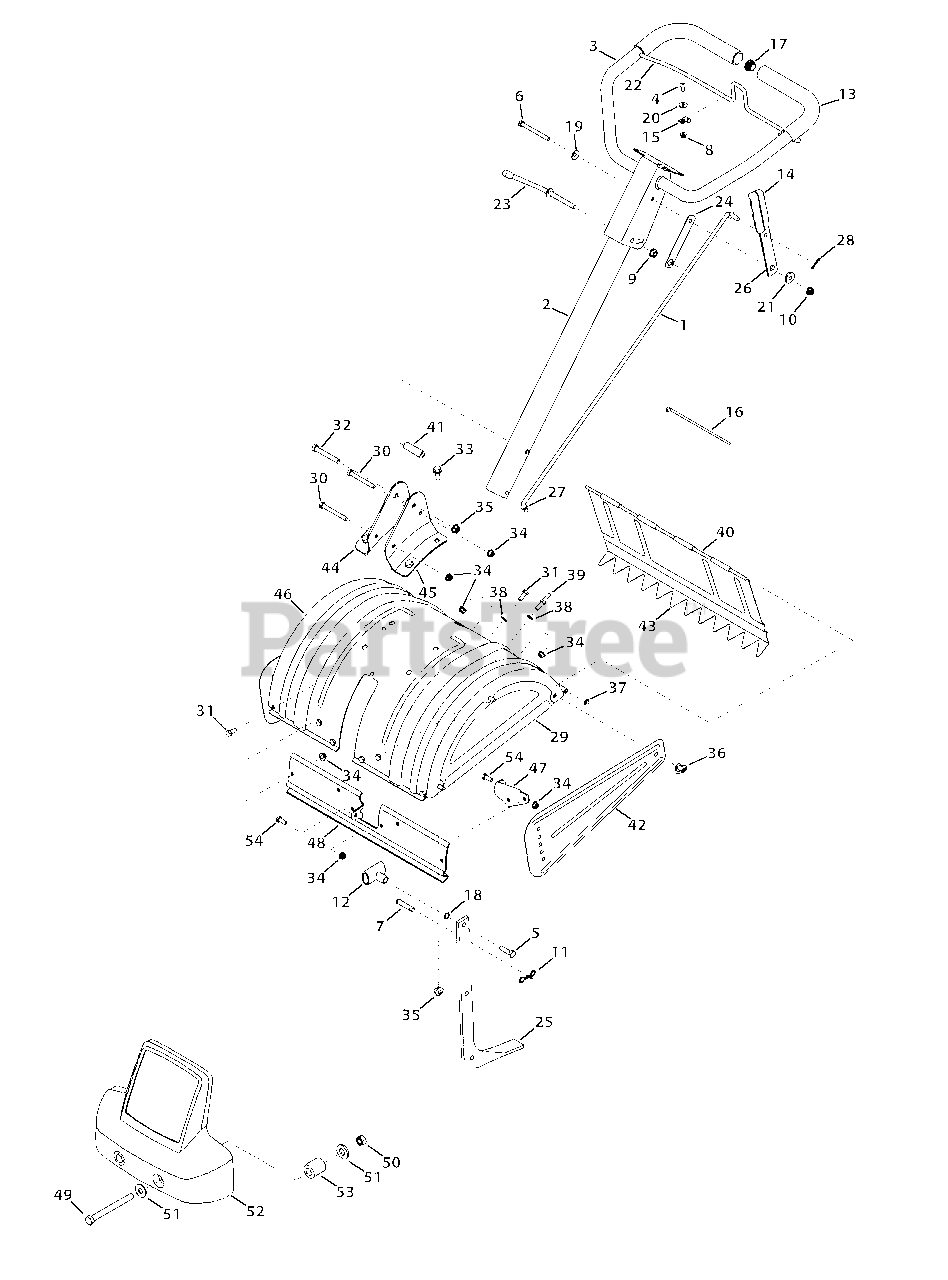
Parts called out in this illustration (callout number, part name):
1	Shaft Rod
2	Lower Handle Tube Assembly
3	Upper Handle Assembly
4	Screw, 1/4-20 x 0.625
5	Hex Head Screw, 3/8-16:1.25
6	Hex Head Screw, 5/16-18 x 3.25
7	Clevis Pin, .375 X 1.75
8	Nylon Hex Lock Nut, 1/4-20
9	Flangelock Nut, 3/8-24
10	Hex Flange Top L-Nut, 5/16-18
11	Internal Cotter Pin
12	Small Tee Knob
13	Foam Grip, .970 x 11.0
14	Grip, .1875 x 1.00
15	Battery Clamp, 5/16
16	Cable Tie, 8.5 LG
17	End Plug
18	Washer, Flat, .385 x .620 x .033
19	Washer, Bell, .340 x .872 x .060
20	Washer, Flat, .260 x .720 x .060
21	Spacer, Shoulder, .50 x .190 x .360 LG
23	Handle Adjustment Crank
24	Hex Nut Retainer Bracket
25	Tiller Depth Control
26	Shaft Rod Lever
27	Washer, Rubber, .33 ID x .87 OD x .125
28	Cotter Pin, .072 x 1.12 LG
29	End Cover Assembly
30	Hex Head Screw, 5/16-18 x 2.75
31	Hex Head Screw, 5/16-18 x .75
32	Hex Head Screw, 3/8-16 x 2.75
33	Hex Head Flange, 3/8-16 x .875
34	Flangelock Nut, 5/16-18
35	Flangelock Nut, 3/8-16
36	Wing Nut, 5/16-18 W/ Bell Washer
37	Speed Nut Cap, 1/4 ROD
38	Washer, Flat, .344 x .62 x .033
39	Screw, Hex, 5/16-18 x .75
40	Tiller Flap Rod
41	Spacer, .322 x .625 x 2.00
42	Side Shield
43	Rear Tine Shield
44	RH Handle Mount Bracket
45	LH Handle Mount Bracket
46	Tine Shield
47	FRT Tine Shield Bracket
48	FRT Tine Shield Spacer Bracket
49	Hex Head Screw, 1/2-13 x 5.50
50	Hex Nut, 1/2-20
51	Washer, 1/2 x 1.25 x .10
52	Counterweight
53	Hub, .636 ID x 1.00 OD x .94
54	Hex Head Screw, 5/16-18 x 1.00
